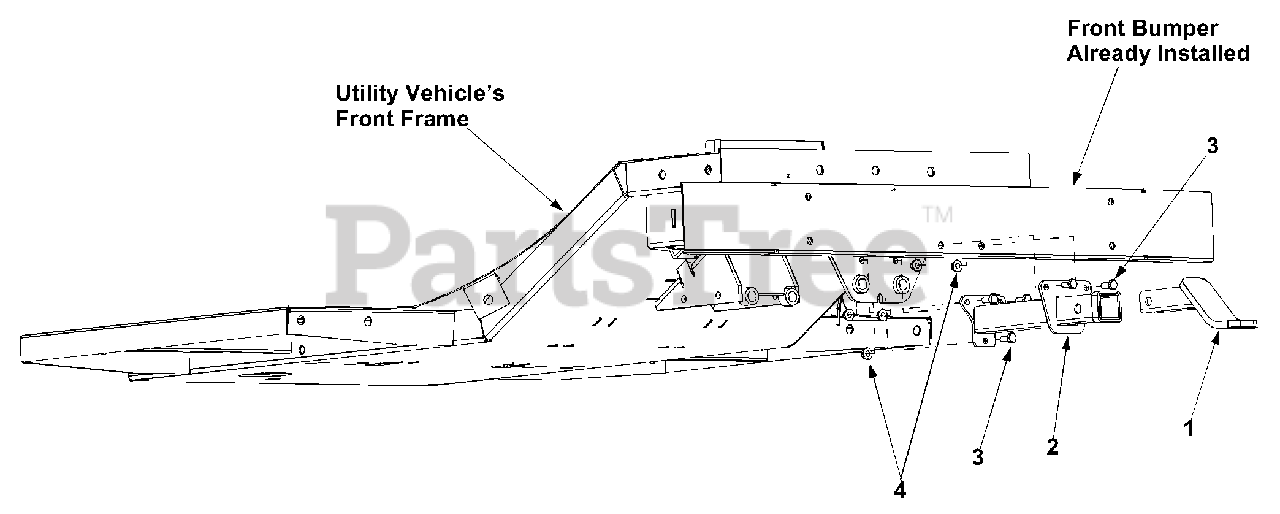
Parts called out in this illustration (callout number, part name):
1	Hitch Accessory
2	Front Hitch Assembly
3	Hex Cap Screw 5/16-18 x .75
4	Flange Lock Nut 5/16-18
